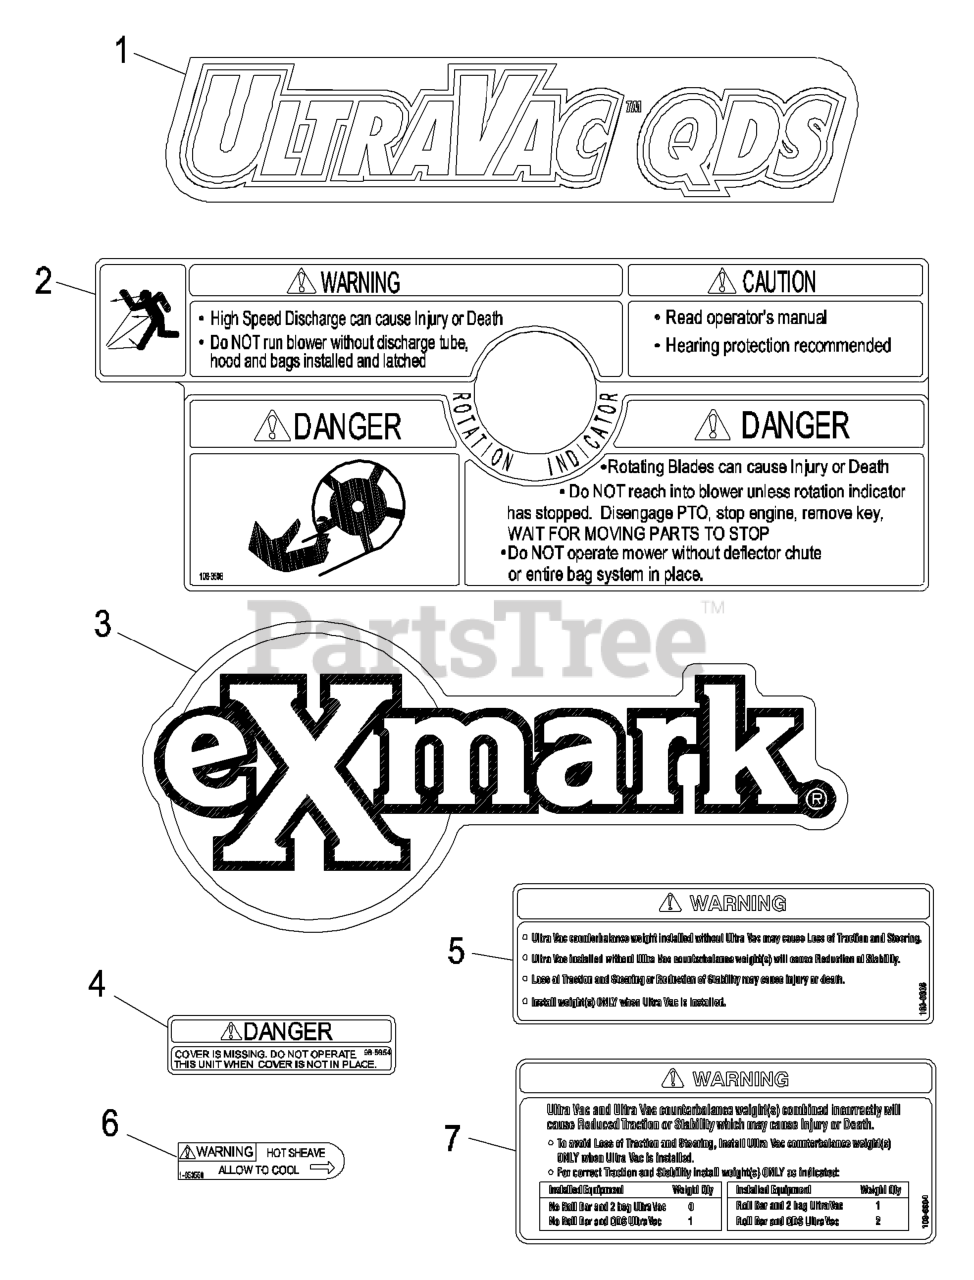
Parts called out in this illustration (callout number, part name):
1	DECAL, ULTRAVAC QDS
2	DECAL-WARNING
3	DECAL, EXMARK LOGO
4	DECAL-COVER, MISSING
5	DECAL,WEIGHT
6	DECAL-WARNING
7	DECAL,WEIGHT
